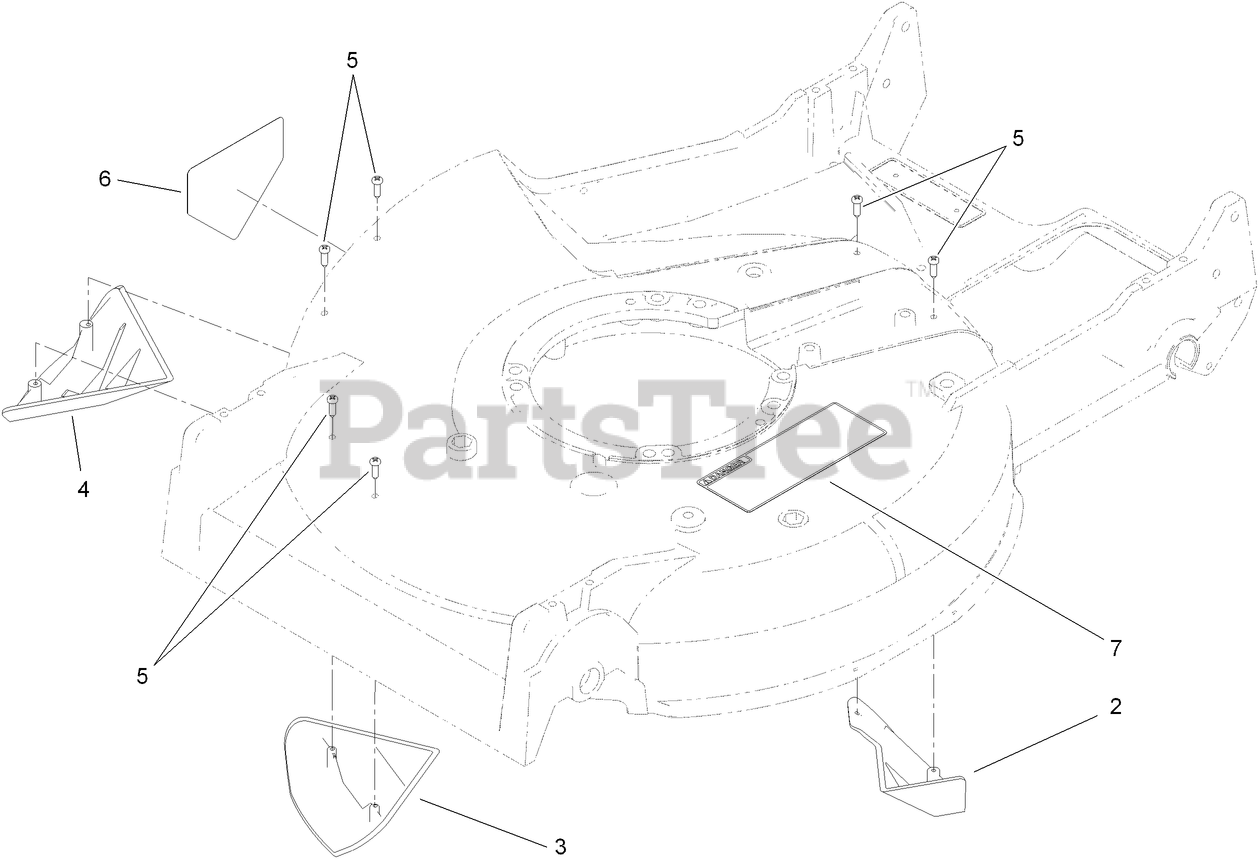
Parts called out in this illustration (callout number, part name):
2	KICKER-REAR
3	KICKER-FRONT
4	KICKER-RH
5	SCREW-PPH
6	DECAL-DANGER
7	DECAL-WARNING
